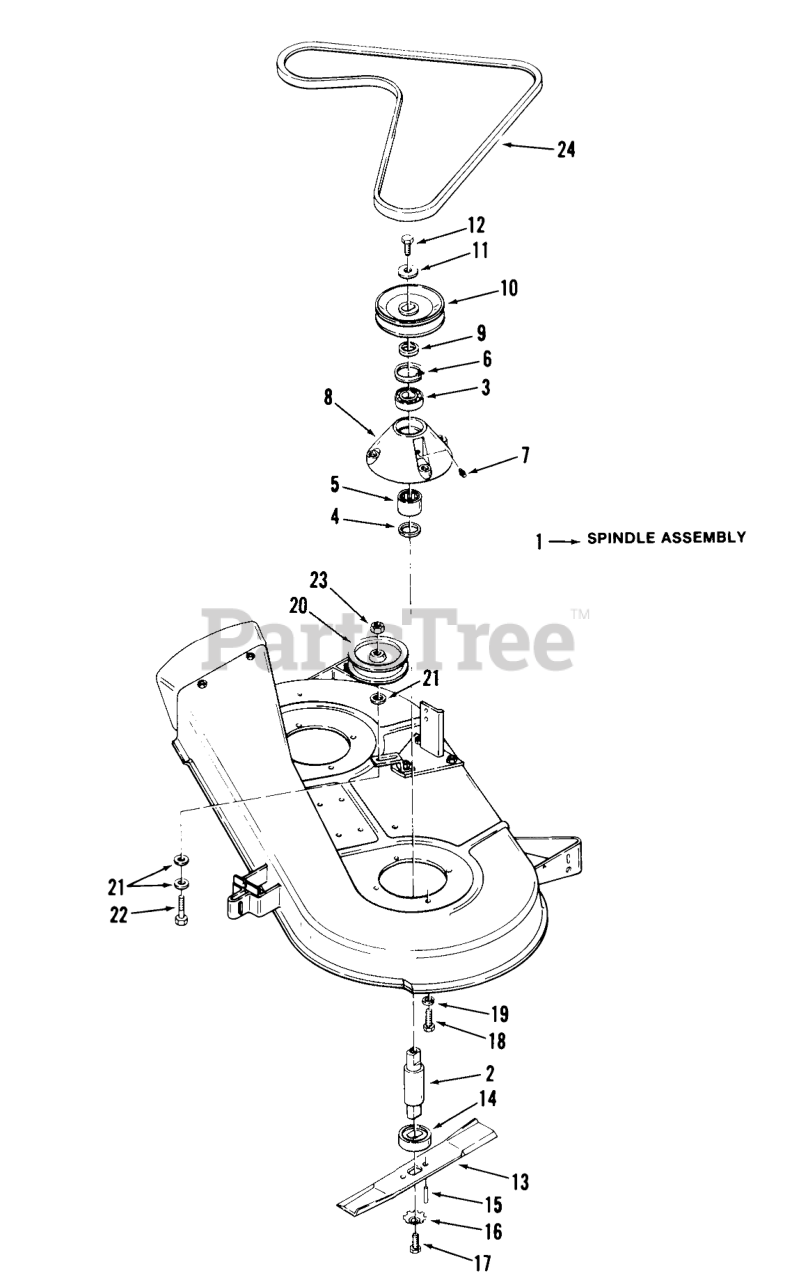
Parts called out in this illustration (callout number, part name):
1	Spindle Assembly (includes parts 2,3,4,5,6,7,& 8)
2	SPINDLE MOWER
3	BEARING-BALL
4	OIL SEAL
5	BEARING-NEEDLE
6	INT SNAP RING
7	Fitting-Grease
8	HOUSING
9	SPACER
10	PULLEY-BLADE
11	WASHER
12	Bolt
13	S/A BLADE KIT
14	Spindle Cup
15	SPIROL ROLL PIN
16	WASHER
17	Bolt
18	Bolt
19	LOCKWASHER
20	Idler Pulley
21	Washer
22	Bolt
23	Nut
24	V-BELT
